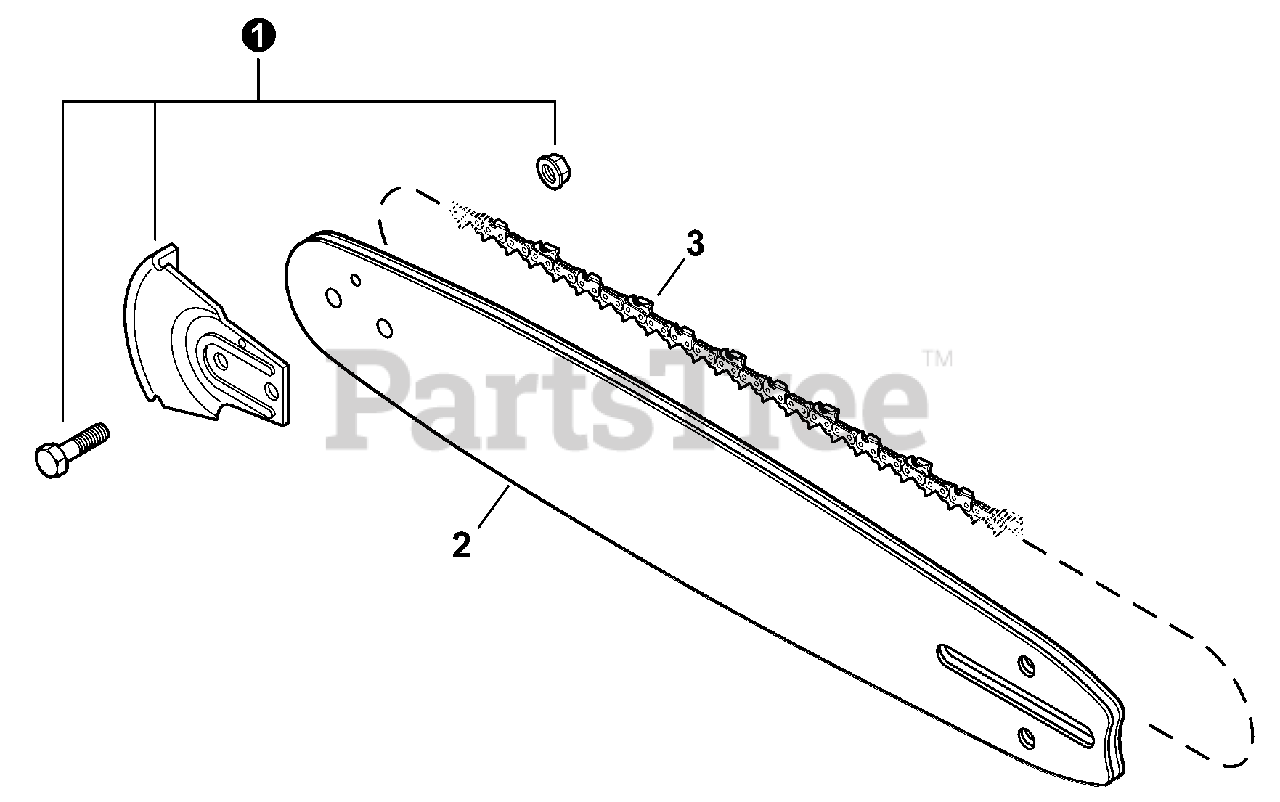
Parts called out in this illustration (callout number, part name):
1	KICK GUARD KIT
2	GUIDE BAR, 14" DOUBLE-GUARD
3	SAW CHAIN 14"
